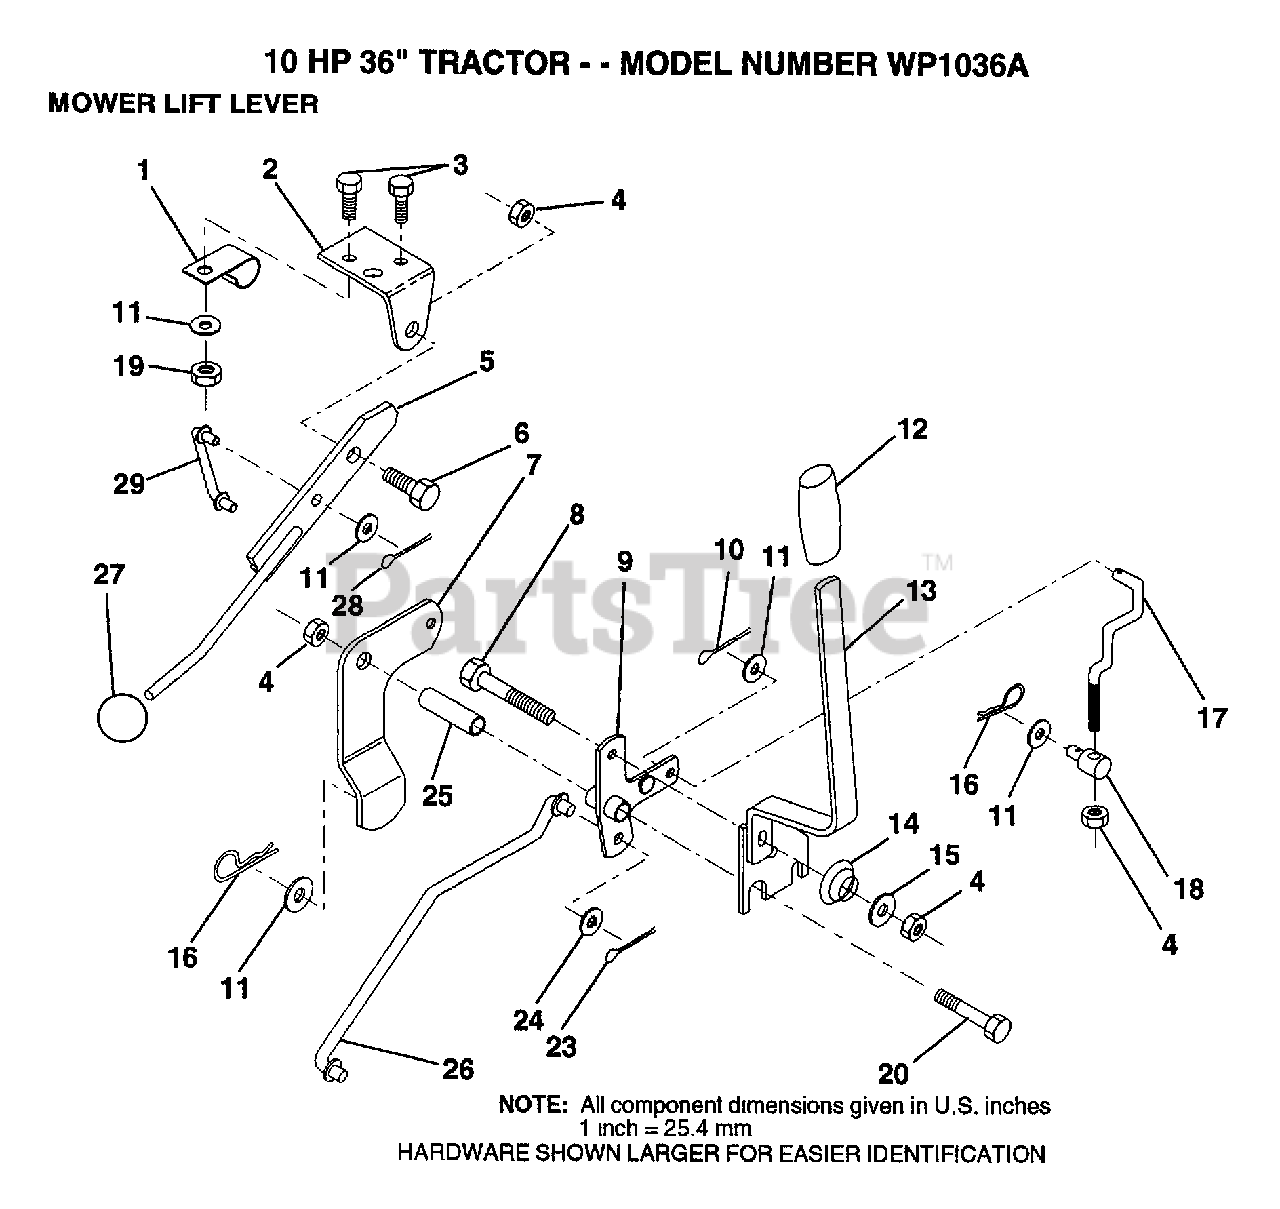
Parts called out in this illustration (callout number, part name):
1	"CLIP,INSULATOR"
2	BRKT CLUTCH
3	BOLT
5	CLUTCH LEVER AS
6	"BOLT, SHOULDER LT"
7	MWR CLUTCH ARM AS
8	BOLT
9	"BELLCRANK,LIFT"
10	COTTER PIN
11	WASHER
13	"HDLE,LIFT T"
14	SPRING COMPRESSIO
15	WASHER T
16	SPRING.RETAINER
17	"LINK,LIFT FRT"
18	TRUNION
20	BOLT
23	PIN COTTER 1/8
25	TUBE SPACER
26	"ROD,MOWER LIFT "
27	KNOB T(3/8 HOLE)
29	CLUTCH LINK
